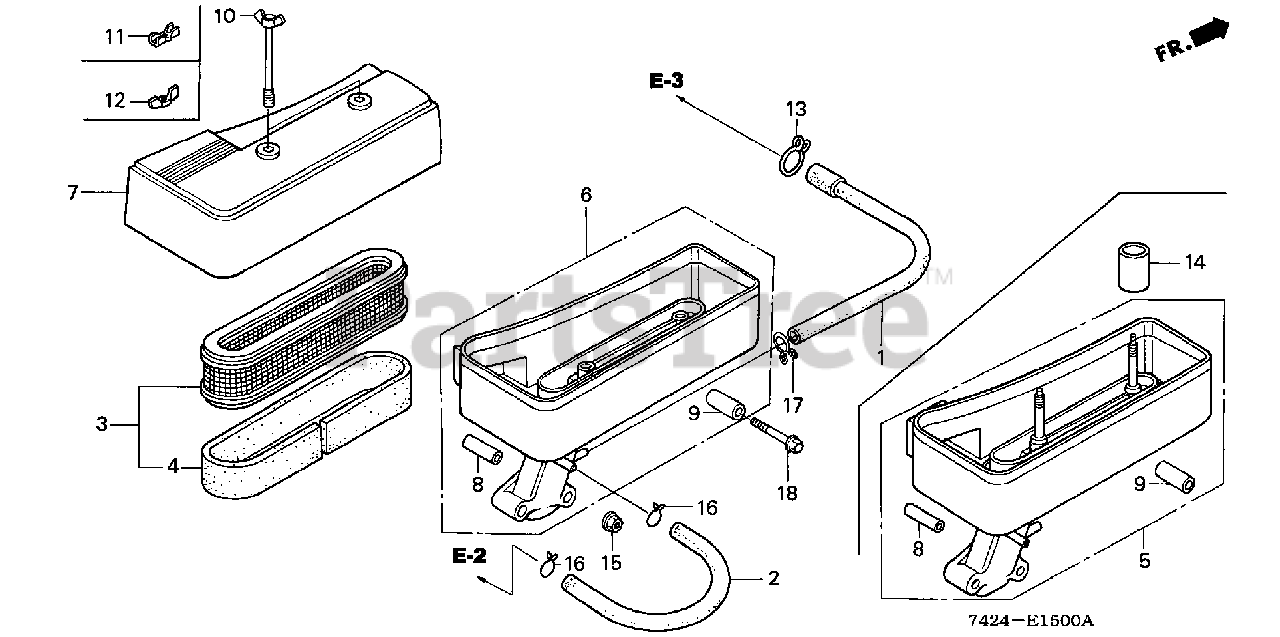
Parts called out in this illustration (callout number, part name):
1	TUBE, BREATHER
2	TUBE A, BREATHER
3	ELEMENT, AIR CLEANER
4	FILTER (OUTER)
5	HOUSING, AIR CLEANER
7	COVER, AIR CLEANER
8	COLLAR, AIR CLEANER
9	COLLAR B, AIR CLEANER
11	WINGNUT, AIR CLEANER COVER
11	WINGNUT (6MM)
13	CLIP, TUBE
14	COLLAR, ENGINE COVER (17MM) (A)
15	NUT, FLANGE (6MM)
16	CLIP, TUBE (B7)
17	CLIP, TUBE (B12)
18	BOLT, FLANGE (6X35)
